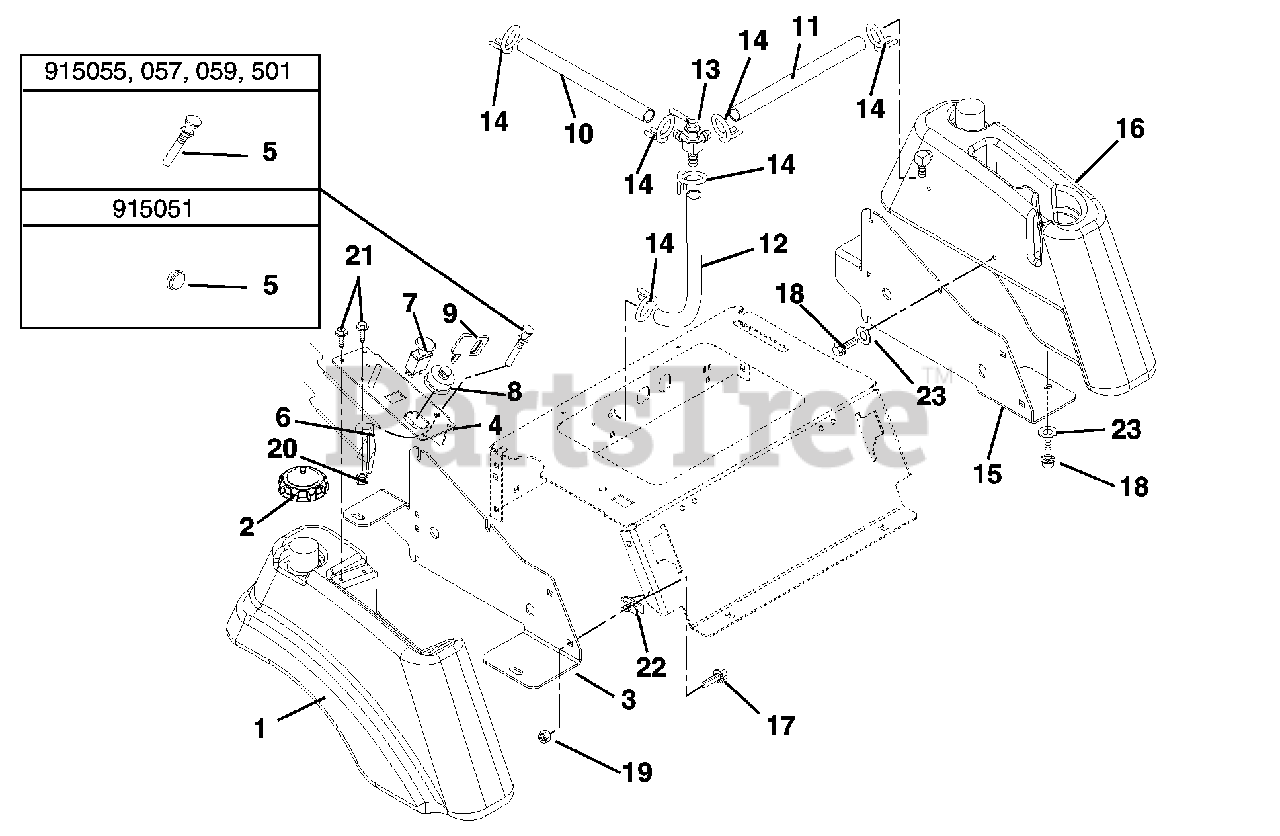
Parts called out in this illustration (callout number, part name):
1	FUEL TANK - RH
2	FUEL CAP
3	SEAT PLATE/TANK SUPPORT RH
4	BKT-CONTROL
5	CHOKE CABLE
6	THROTTLE CABLE
7	SWITCH, CLUTCH
8	KEY SWITCH
9	KEY -W/CAP
10	GAS LINE-BULK 1/4" I.D.
11	GAS LINE-BULK 1/4" I.D.
12	GAS LINE-BULK 1/4" I.D.
13	VALVE, FUEL
14	CLAMP-HOSE WIRE .490/.510X.116
15	SEAT PLATE LH
16	FUEL TANK - LH
17	@BLT-RDHDSQNK .38-16X1.00 G5YZ
18	BLT-SERHFWH .312-18X.75 YWZC
19	@NUT-LK-NYL-FLG .38-16 YWZC
20	@NUT-LK-NYL 10-24 W/INSRT YWZC
21	@SCR-MCH 10-24X.50 HWH YWZC
22	RETAINER, .38 PUSH-ON
23	WSHR-FL-STL .328X1.0X.094 YWZC
